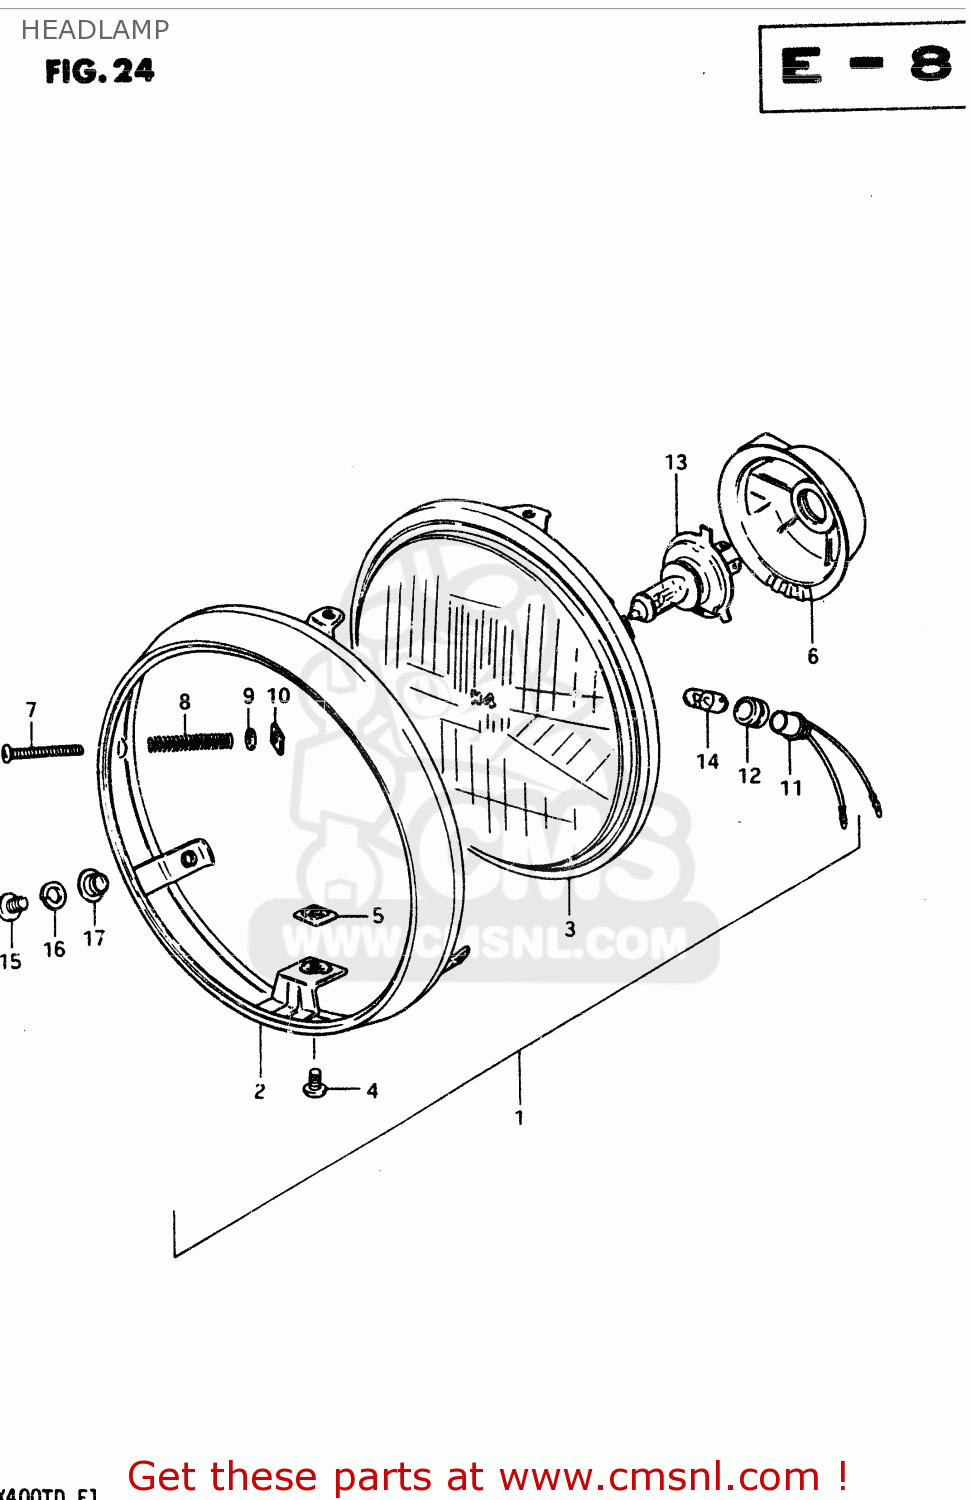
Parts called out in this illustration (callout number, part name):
1	HEADLAMP ASSY
2	RIM
3	LAMP UNIT
4	SCREW
5	NUT,ADJUSTING
6	COVER,SOCKET
7	SCREW
8	SPRING
9	WASHER
10	NUT,HEADLAMP ADJUSTER
11	SOCKET
12	JOINT,RUBBER
13	BULB(12V60/55W,H4)
14	BULB(12V4W)
15	SCREW
16	WASHER,LOCK
17	WASHER
